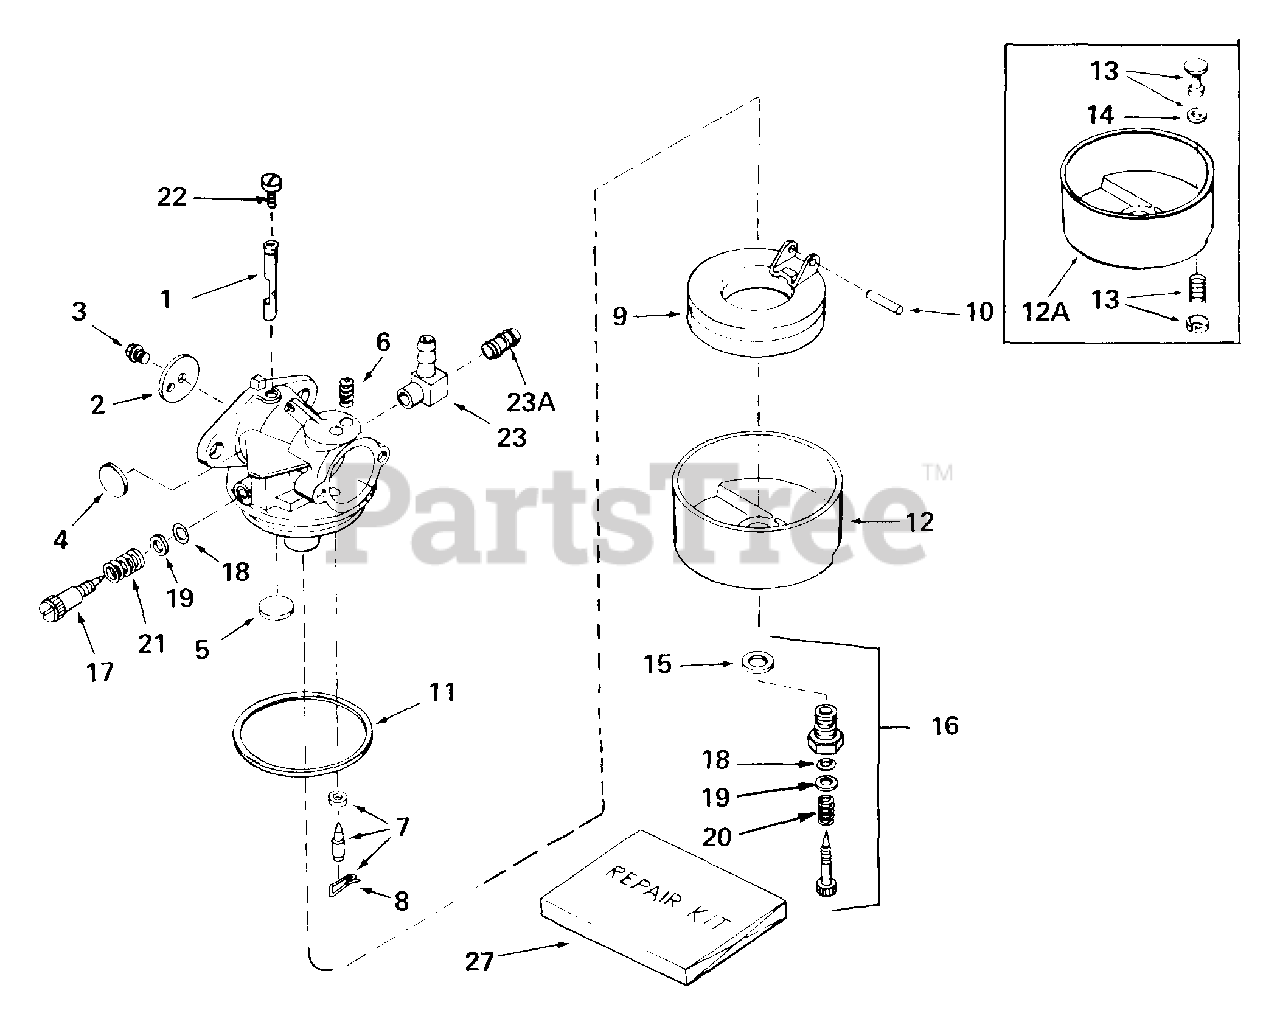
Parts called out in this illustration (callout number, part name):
1	"Shaft, Throttle
2	Shutter, Throttle
3	Screw, Throttle shutter
4	Plug, Welch
5	Plug, Welch
6	Spring, Choke positioning
7	Inlet Needle, Seat & Clip
8	Clip, Inlet needle
9	Float, Carburetor.
10	Shaft, Float
11	Gasket, Bowl-to-body
12	Bowl Float
15	Gasket, Bowl-to-Body
16	Adjustment Screw Assy., Main
17	Screw, Idle adjustment
18	"O" Ring, Adjustment screw
20	Spring, Adjustment screw
21	Spring, Adjustment screw
23	Fitting, Fuel Inlet
23	Fitting, Fuel inlet
27	Repair Kit
